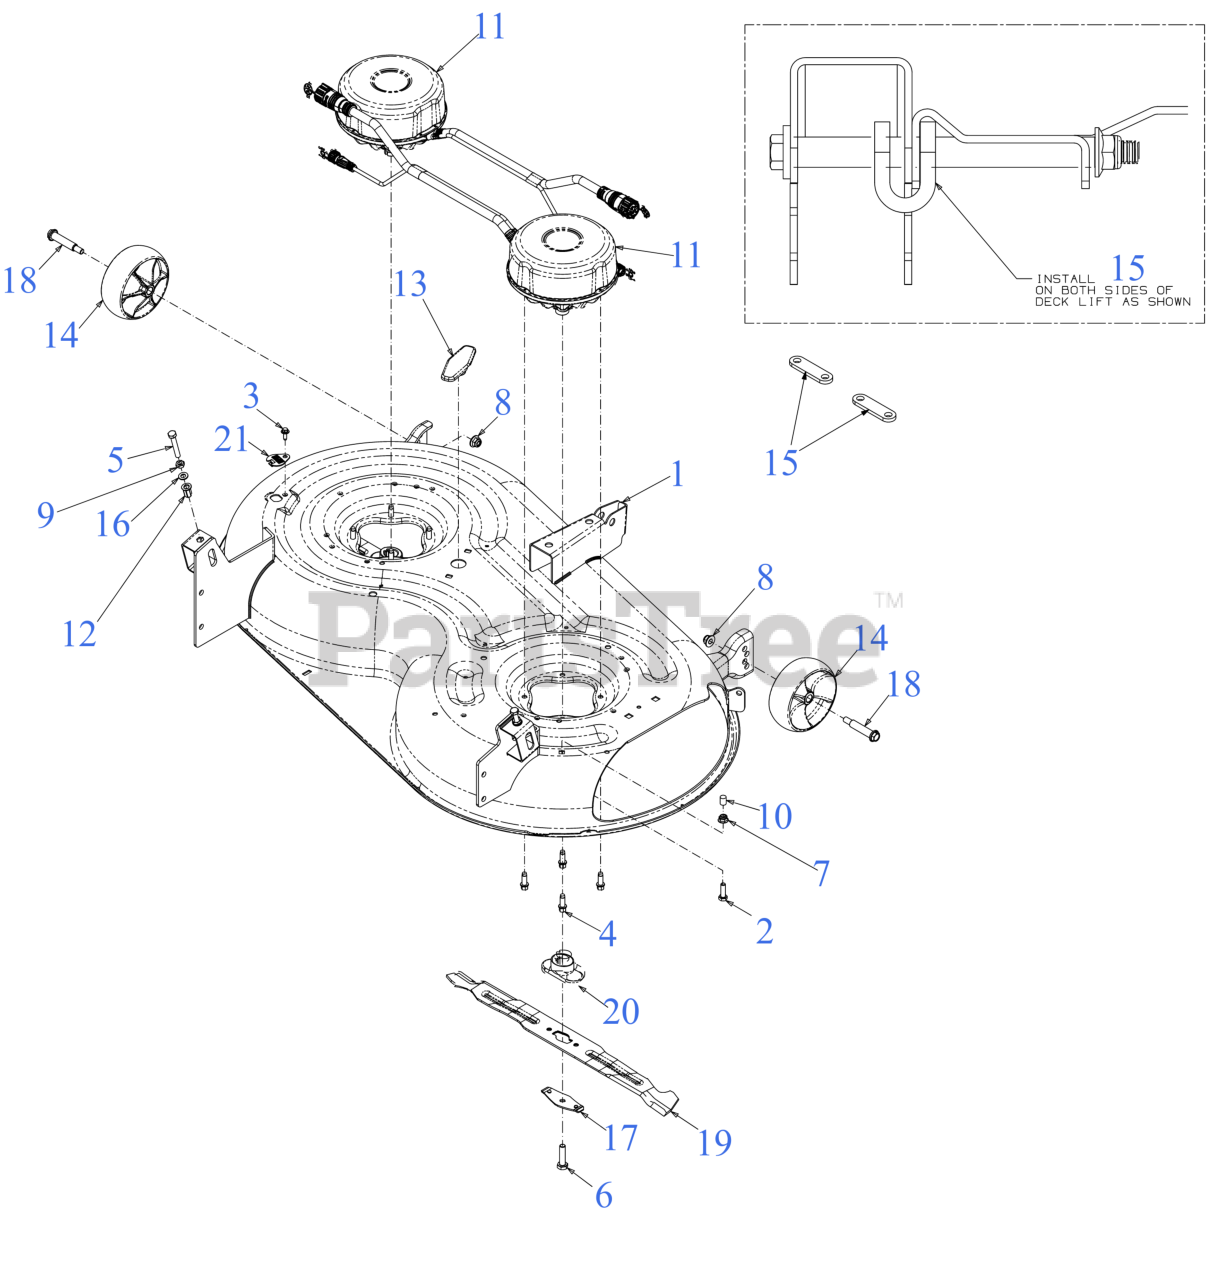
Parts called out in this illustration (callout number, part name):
1	42" DECK ASSEMBLY
2	SCREW 5/16-18 x 1.0 GR5
3	SCREW M6-1 x .625
4	SCREW 5/16-18 x .875
5	SCREW-FULL THREAD 5/16-18 GR5
6	SCREW 3/8-24 x 1.50 GR8
7	FLANGE LOCK NUT 5/16-18
11	48V ELECTRIC DECK MOTOR
12	NUT RIVET 5/16-18
14	DECK WHEEL (5.0 DIA x 1.875)
14	Cub Cadet 5" DECK WHEEL (06305A) (W/BOLT)
15	DECK LIFT UPSTOP
16	FLAT WASHER
17	BLADE BELL SUPPORT
18	SHOULDER BOLT (.50 X 2.0 x 3/8 -16)
19	21.18" MULCH BLADE (S SHAPE CENTER HOLE)
19	Cub Cadet 42" BLADE SET
20	BLADE ADAPTER (#6 X 1.19 W/S)
21	DECK WASH PLUG
